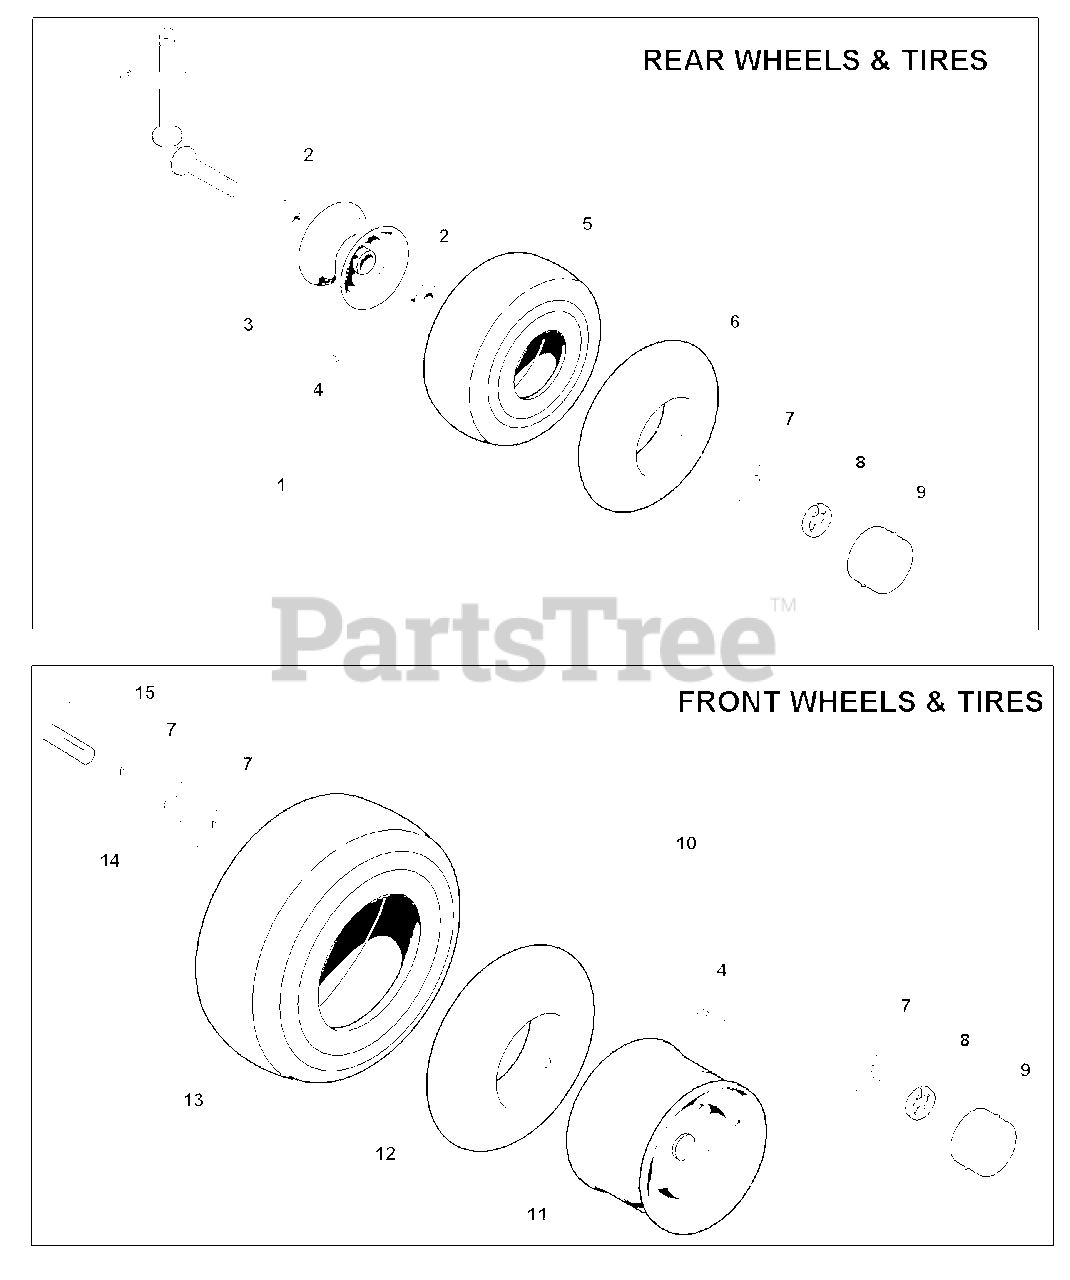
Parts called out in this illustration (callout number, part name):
1	WHEEL & TIRE ASEMBLY, Rear, (Includes Ref. Nos. 2, 3, 4, 5, & 6)
2	BEARING, Ball
3	WHEEL & BUSHINGS ASSEMBLY, (Includes Ref. No. 2)
4	VALVE STEM & CAP ASSEMBLY
5	TIRE, 15 X 6.00, 6 SUPER TURF TL
6	TUBE, Tire, 4.10/3.50, Rear
8	RING, "E", External
10	WHEEL & TIRE ASSEMBLY, Front, (Includes Ref. Nos. 4, 11, 12, & 13)
11	WHEEL, 7.00 x 8.00
12	TUBE, Tire, 16 x 6.50
13	TIRE, 18 x 9.50, 8 SUPER TURF TL
15	KEY, Parellel
